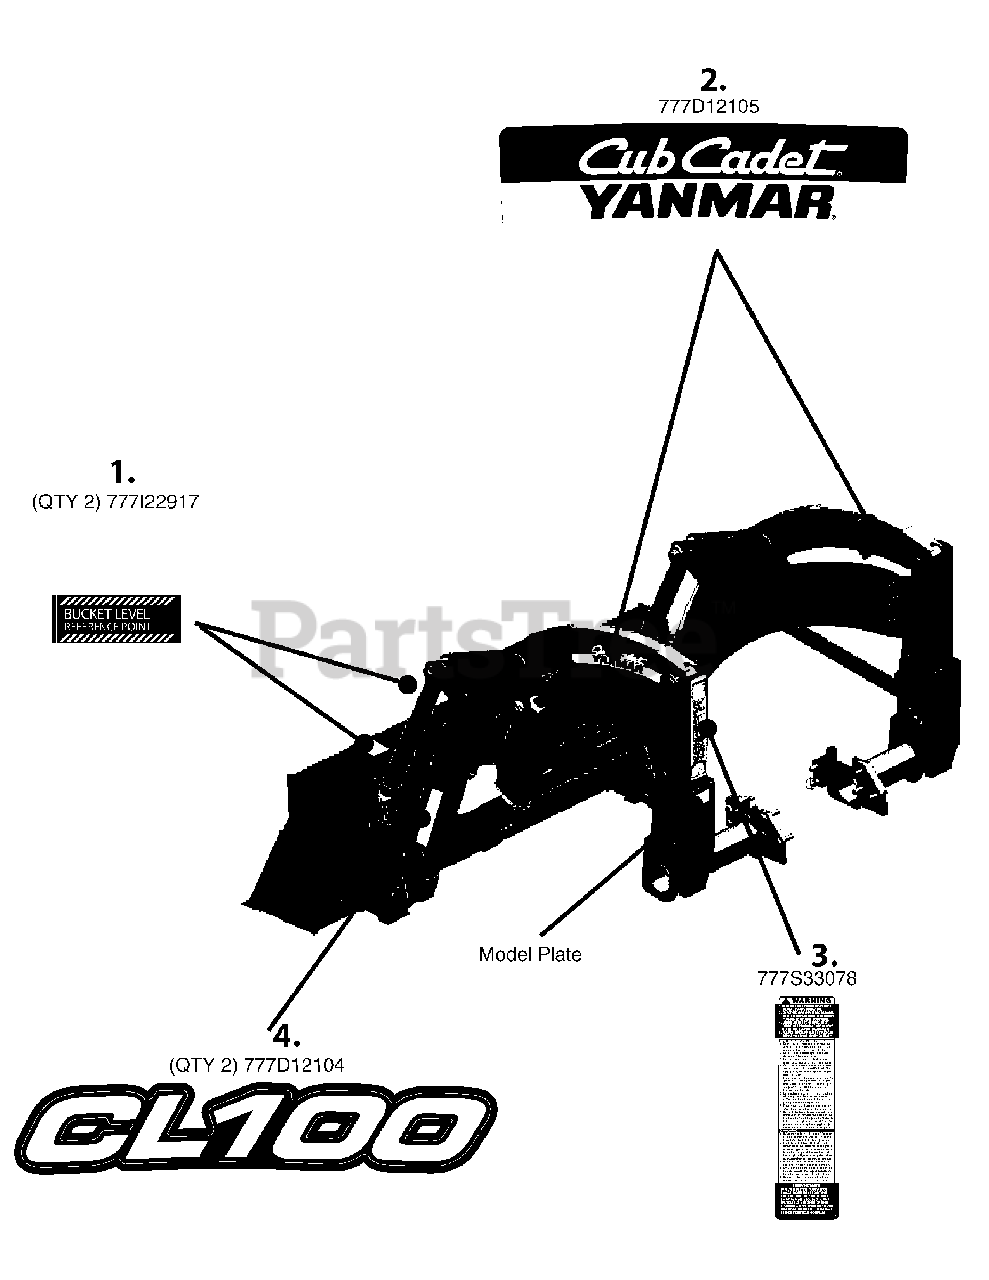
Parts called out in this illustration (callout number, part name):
1	LABEL-BUCKET LEVEL
2	LABEL-CUB YANMAR
3	LABEL-LH MAST WARNG
